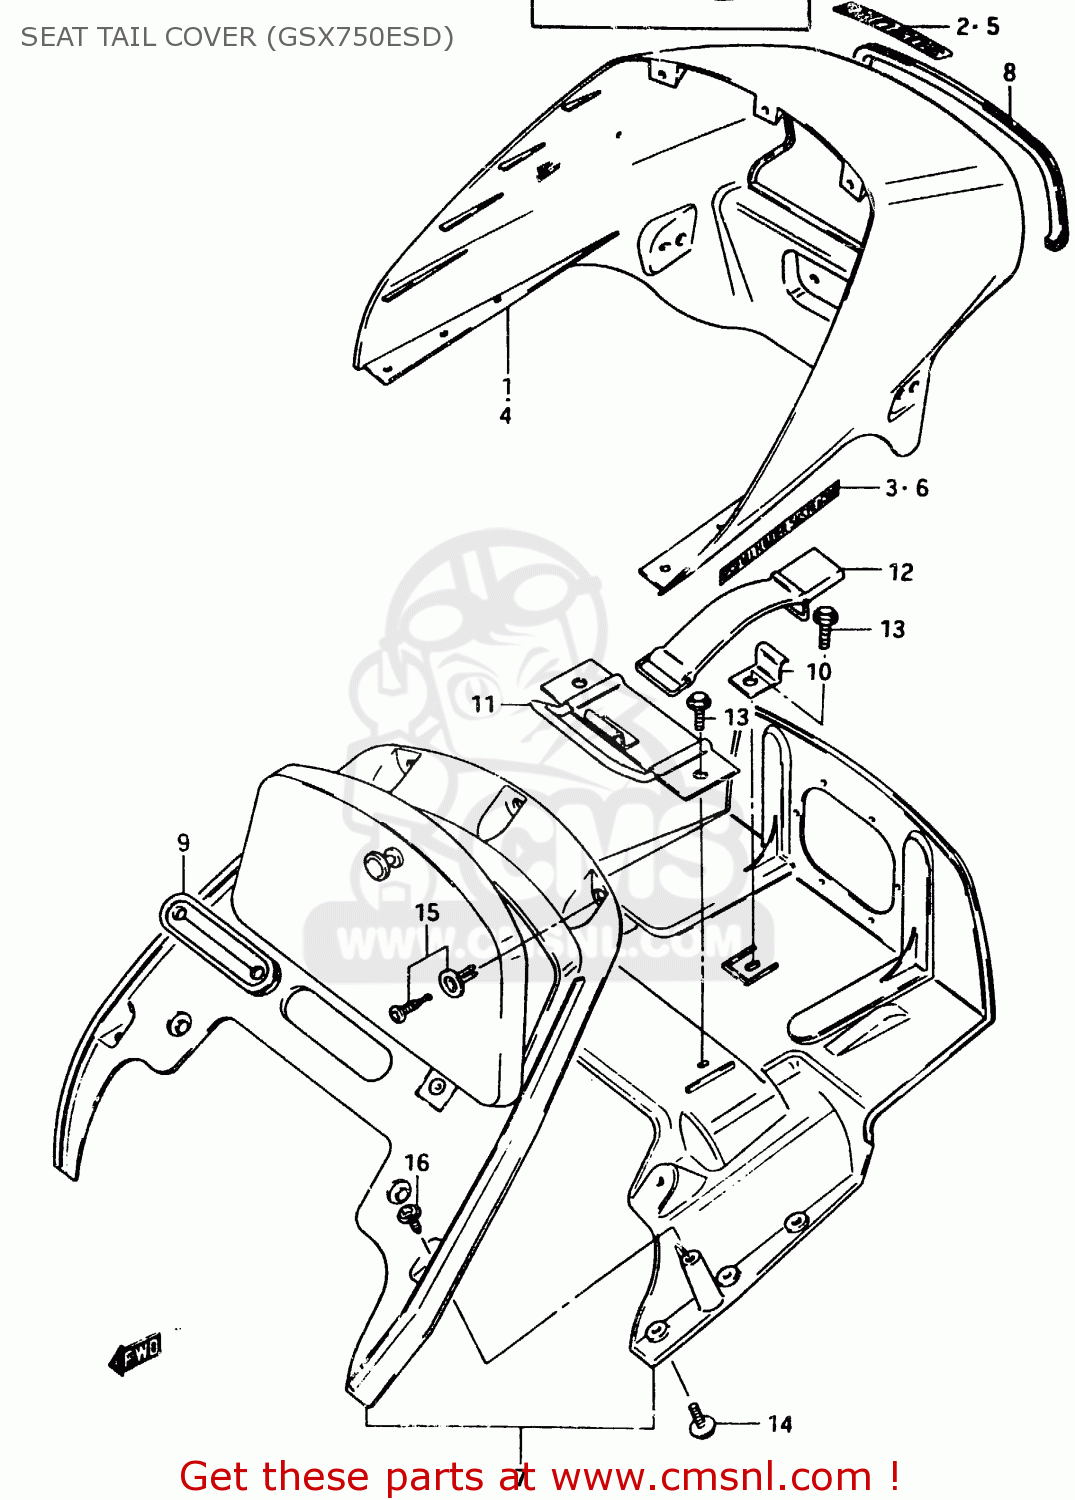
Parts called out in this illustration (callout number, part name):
1	TAIL COVER, SEAT (BLUE)
2	EMBLEM(WHITE)
3	EMBLEM
4	COVER,SEAT TAI
5	EMBLEM(WHITE)
6	EMBLEM
7	FLAP,SEAT TAIL COVER
8	MOLDING,SEAT TAIL COVER
9	GROMMET,SEAT TAIL COVER
10	PLATE,CHAIN LOCK HOLDER
11	PLATE,SEAT HOOK
12	BAND
13	BOLT
14	SCREW
15	CLIP
16	SCREW
